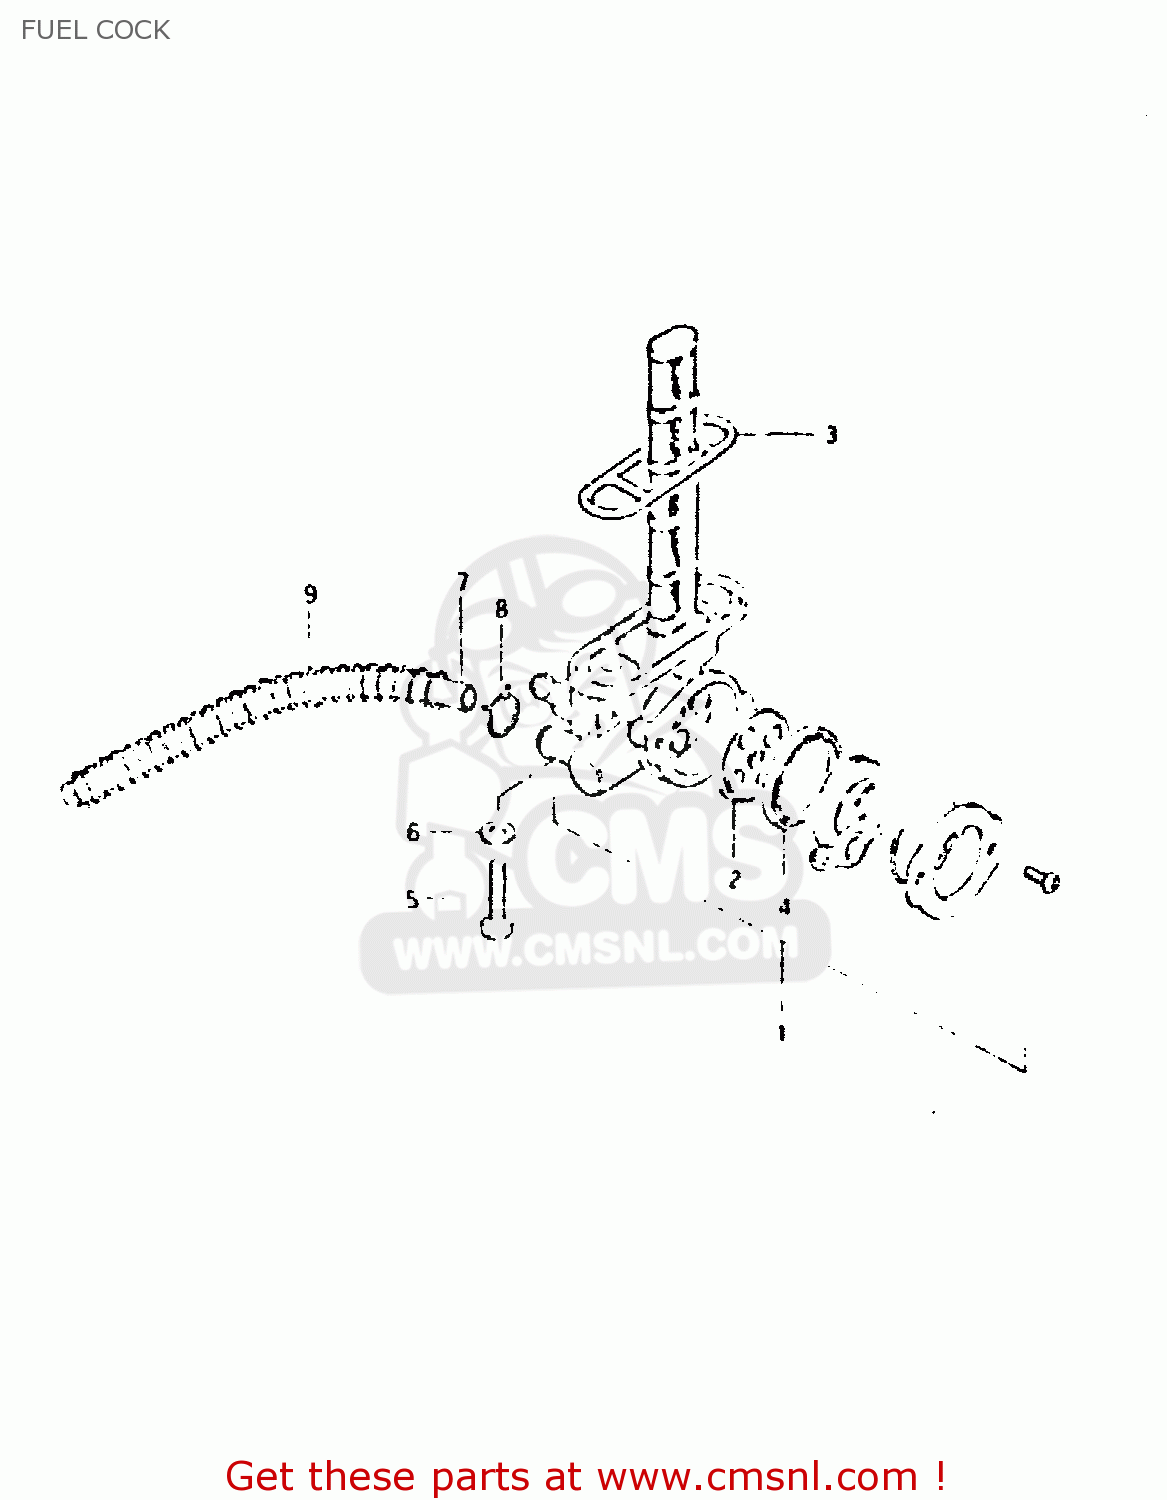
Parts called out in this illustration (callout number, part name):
1	COCK ASSY,FUEL
2	GASKET (NAS)
3	GASKET, FUEL COCK (NAS)
4	V SEAL,FUEL COCK
5	SCREW
6	GASKET
7	HOSE
8	CLIP
9	SPRING
